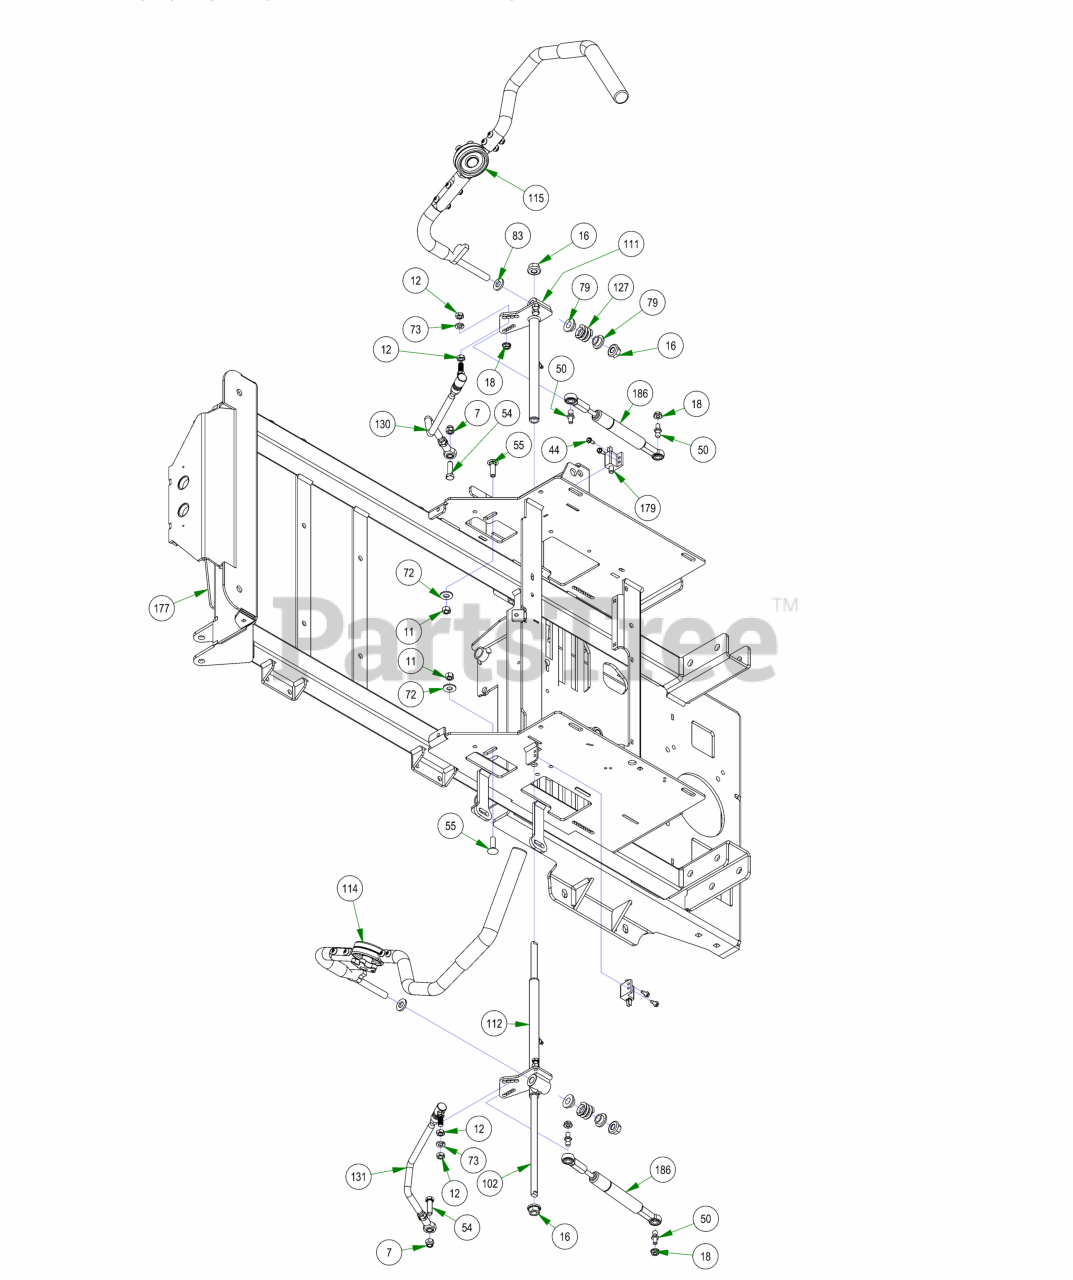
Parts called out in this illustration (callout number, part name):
7	3/8-16 NYLON INSERT LOCKNUT ZINC
11	3/8-16 HEX NUT ZINC
12	3/8-24 HEX NUT ZINC YELLOW
16	1/2-13 NYLON INSERT FLANGE LOCKNUT ZINC
18	5/16-18 HEX SERRATED FLANGE NUT HARD/ZINC
44	12-24 X 1/2 HEX WASHER UNLSOT F TCS ZINC
50	10mm Damper Ball Stud-Steering
54	3/8-16 X 1-1/4 HEX CAP SCREW (GR.5) ZINC
55	3/8-16 X 1-1/4 CARRIAGE BOLT ZINC
72	3/8 FLAT WASHER USS (1" OD) ZINC
73	3/8 SPLIT LOCKWASHER ZINC
79	.525 ID SHOULDER WASHER NYLON
83	.505 ID X 1.000 OD X .125 THICK FLAT WASHER NYLON
102	2021 Maverick Steering Actuator Rod
111	2021 Maverick Drive Arm Actuator RH Assembly
112	2021 Maverick Drive Arm Actuator LH Assembly
114	2018 Adjustable Steering Arm - Left
115	2018 Adjustable Steering Arm - Right
127	Drive Lever Spring
130	Push Rod-Right
131	Push Rod-Left
177	2023 Maverick Frame - Painted
179	Safety Switch
186	Steering Damper
